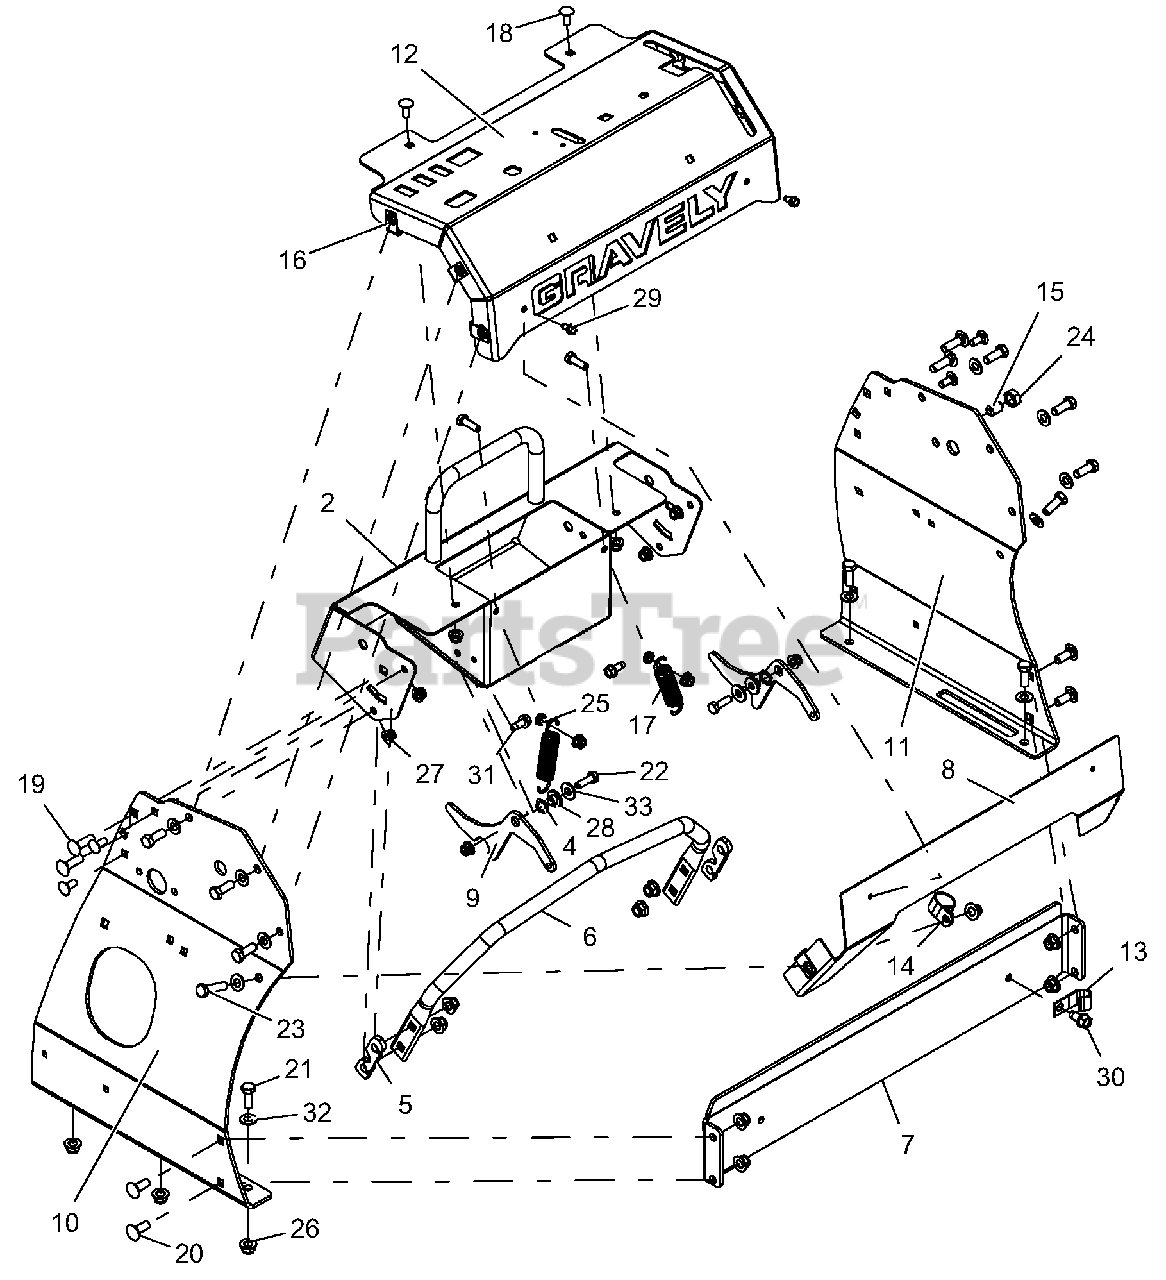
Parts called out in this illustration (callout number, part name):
2	WLDMT, CONTROL PANEL, PRO-STANCE
4	WAVE WASHER .531 x .781 x .125 FH
5	SHIM, BAR 5 DEG SPEED - BLACK
6	STOP, FORWARD STEERING
7	STIFFENER, TOWER
8	PLATE, FRONT BACKER
9	LATCH, PAD MOUNT
10	PANEL, TOWER RH, PRO-STANCE
11	PANEL, PROSTANCE LH TOWER
12	PANEL, CONTROL - PRO-STANCE CARB
14	CLAMP, CUSHIONED STEEL REV
15	BALL SPRING PLUNGER, .500-13
16	NUT, RTNR .375-16 x .37
17	SPRG, EXTENSION
18	BLT-RDHDSQNK .31-18 x .75 G5 YWZC
19	BLT-RDHDSQNK .38-16 x 1.25 G5 YWZC
20	BLT-RDHDSQNK .38-16 x 1.00 G5 YWZC
21	BLT-HEX .38-16 x 1.00 GR5 YWZC
22	BLT-HEX .31-18 x 1.00 GR5 YWZC
23	BLT-HEX .38-16 x 1.50 GR5 YWZC
24	NUT, JAM .500-13 YWZC
25	@NUT-LK-CTR-JAM .31-18 YWZC
26	NUT-LK-NYL-FLG .38-16 YWZC
27	NUT-LK-NYL-FLG .31-18 YWZC
28	BSHG, FLG .32 x .500 .344 x .880
29	SCR-TAP .25-20 x .50 HWH TR YWZ
30	SCR-TAP .38-16 x .75 HWH TR YWZ
31	SCR-TAP .31-18 x .75 HWH TR YWZ
32	WSHR-FL-STL .406 x .812 x .065 YWZ
33	WSHR-FL-STL .38 x .875 x .083 YWZC
